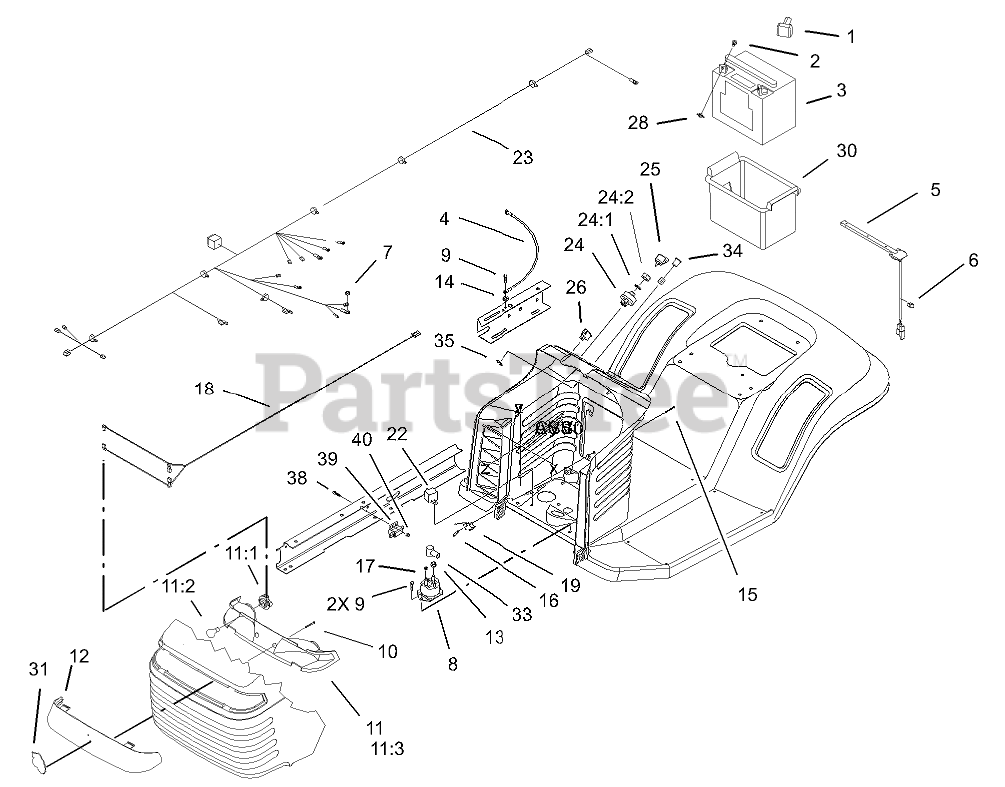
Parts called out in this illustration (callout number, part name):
1	BOOT-TERMINAL
2	SCREW-HH
3	BATTERY-155 CCA
4	WIRE ASM
5	SWITCH-SEAT
6	CLIP-RETAINER, WIRE
7	NUT-KEPS
8	SOLENOID
9	SCREW-HWH
11	HEADLIGHT REFLECTOR ASM
11:1	SOCKET-LIGHT
11:2	BULB
11:3	REFLECTOR-LIGHT
12	LENS-HEADLIGHT
13	NUT-KEPS
14	WASHER-LOCK/EXT
15	SCREW-HH
16	NUT-SPEED
17	NUT-KEPS
18	HARNESS-HEADLIGHT
19	SWITCH-MICRO
22	RELAY
23	HARNESS-WIRE
24	Key Switch ASM
24:1	WASHER-TOOTH, INTERNAL
24:2	NUT-HH
25	KEY-IGNITION
26	SWITCH-ROCKER
28	NUT-WING
30	BOX-BATTERY
31	EMBLEM
33	BOOT-INSULATOR, TERMINAL
34	LIGHT-INDICATOR
35	CLIP-RETAINER
38	SCREW-HSH
39	SWITCH-POLE, SINGLE
40	NUT-LOCK, NI
